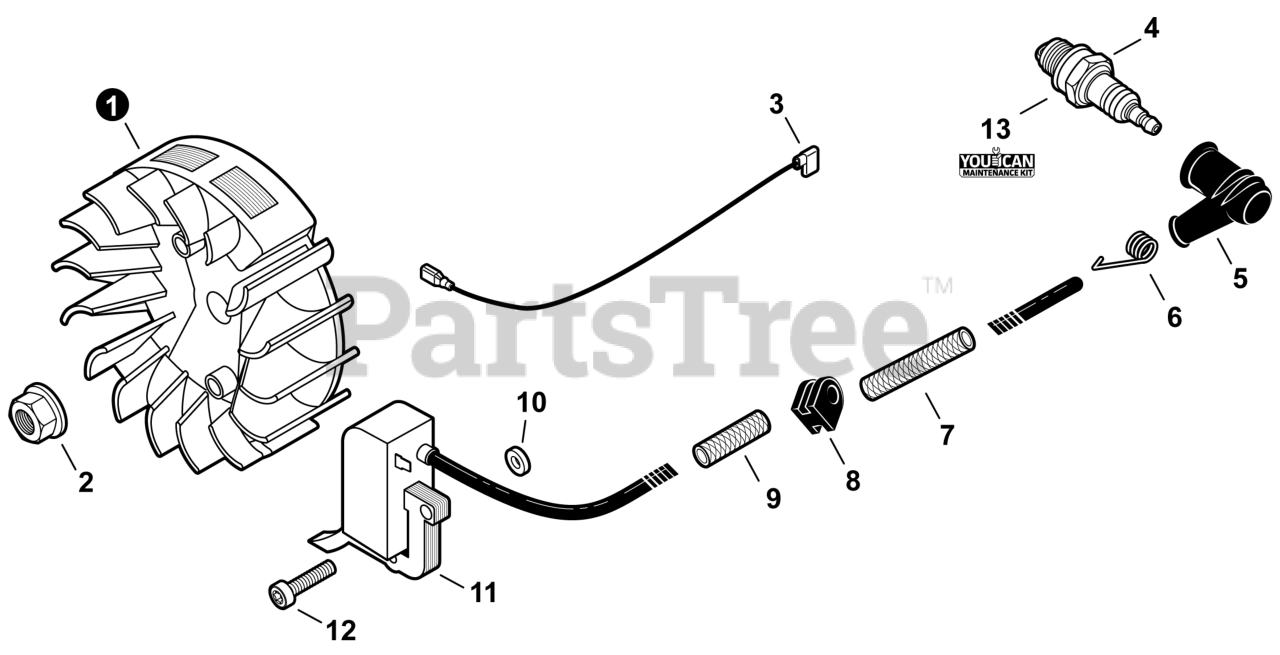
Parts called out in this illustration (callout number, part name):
1	FLYWHEEL
2	NUT, FLANGE M8
3	LEAD - IGNITION
4	SPARK PLUG - BPMR8Y
5	CAP, SPARK PLUG
6	TERMINAL, SPARK PLUG
7	TUBE, INSULATOR 7x8.6x40
9	TUBE, INSULATOR 7x8.6x30
10	WASHER 5.2x12x3
11	COIL, IGNITION
12	BOLT, TORX 5x20
13	TUNE-UP KIT - YOUCANT
